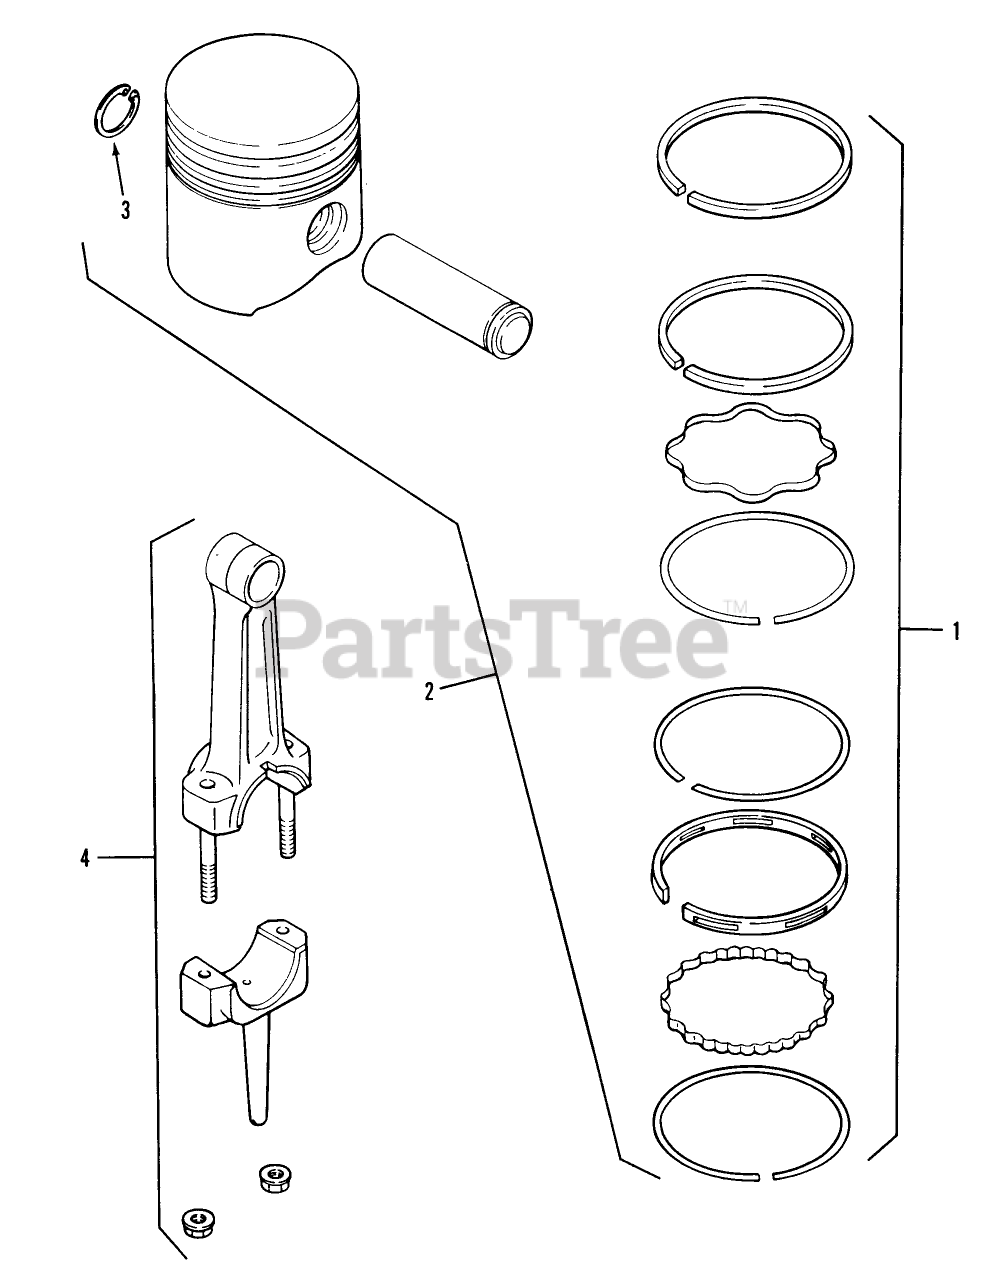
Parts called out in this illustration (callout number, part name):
1	Ring set-Std. .003 (Svc.)
2	Piston wiring Set Std. 312
3	Retainer-Piston Pin
4	Connecting Rod Std. 312
